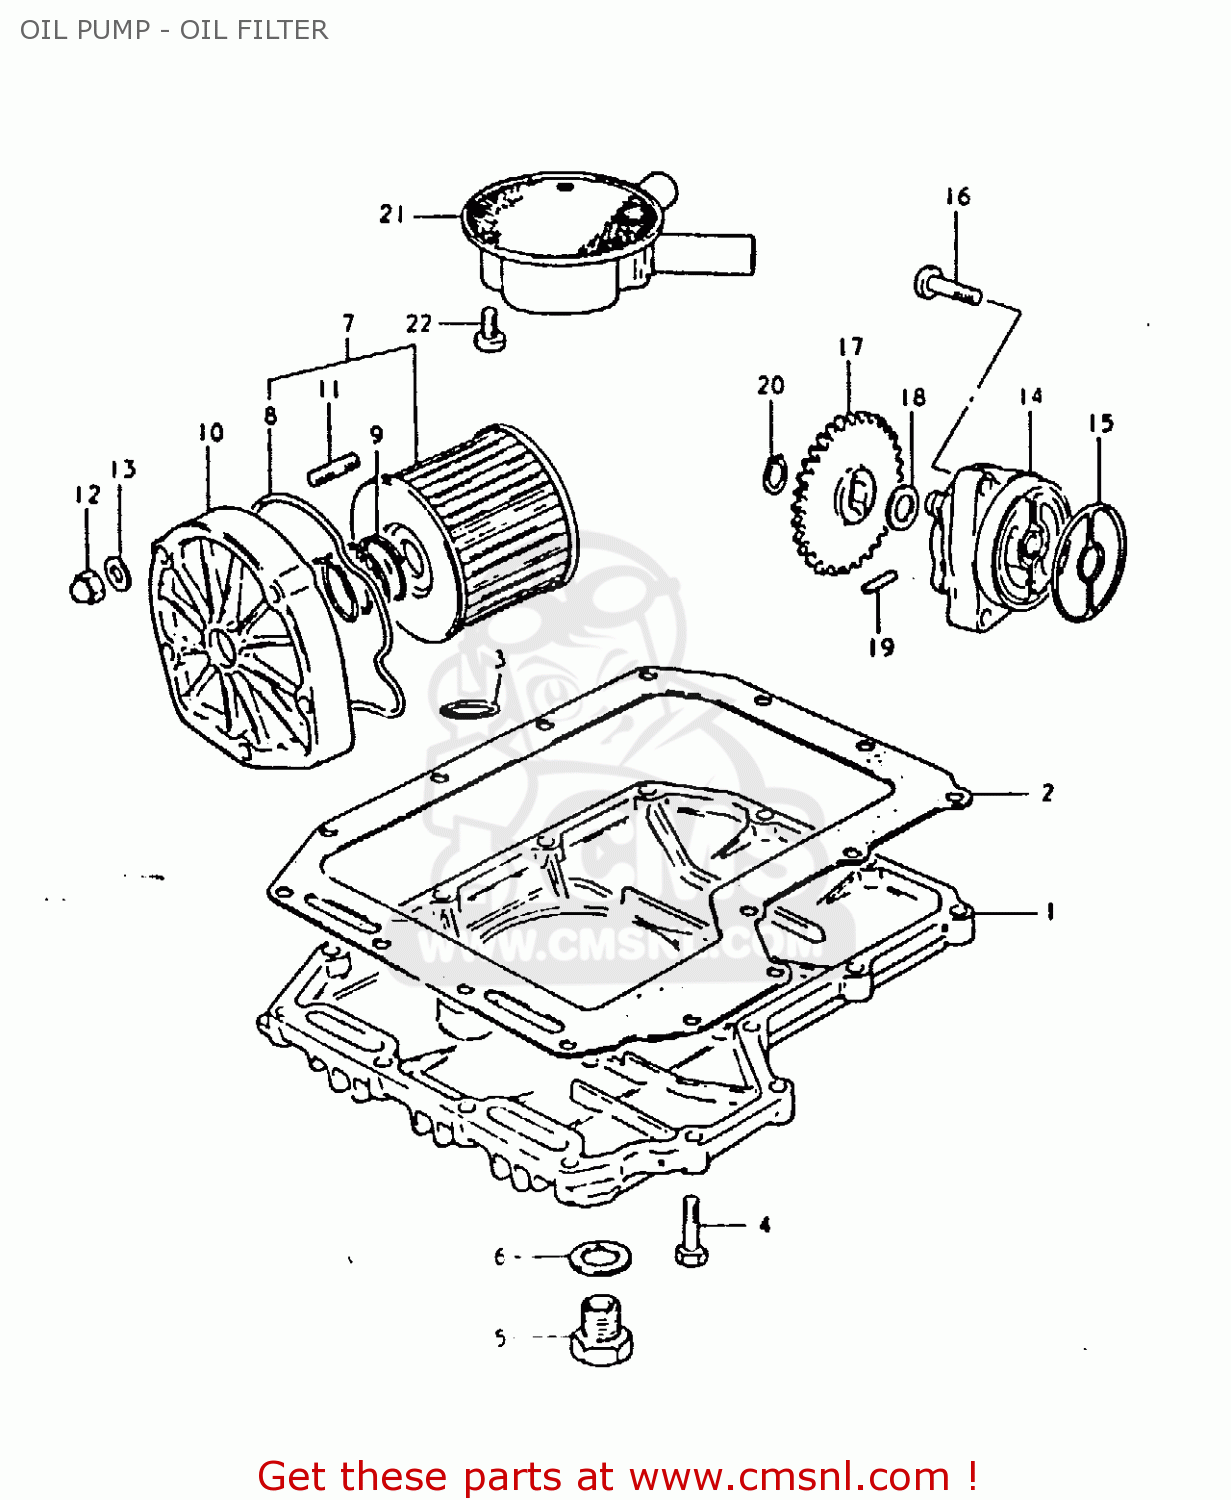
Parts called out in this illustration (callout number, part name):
1	PAN,OIL
2	GASKET,OIL PAN (MCA)
3	O RING(D:3.2,ID:12.9)
4	BOLT
5	PLUG
6	GASKET(14X19.2X2) (NAS)
7	FILTER SET, ENGINE OIL
8	O RING,OIL FILTER CHAMBER CAP
9	SPRING
10	CAP,ENG OIL FLTR OUTER CHAMBER
11	STUD 6X25
12	NUT
13	WASHER
14	PUMP ASSEMBLY,OIL
15	O-RING,OIL PUMP
16	SCREW
17	GEAR,OIL PUMP DRIVEN
18	SHIM
19	PIN(4X15.8)
20	CIRCLIP
21	STRAINER,ENGINE OIL
22	SCREW 6X12
